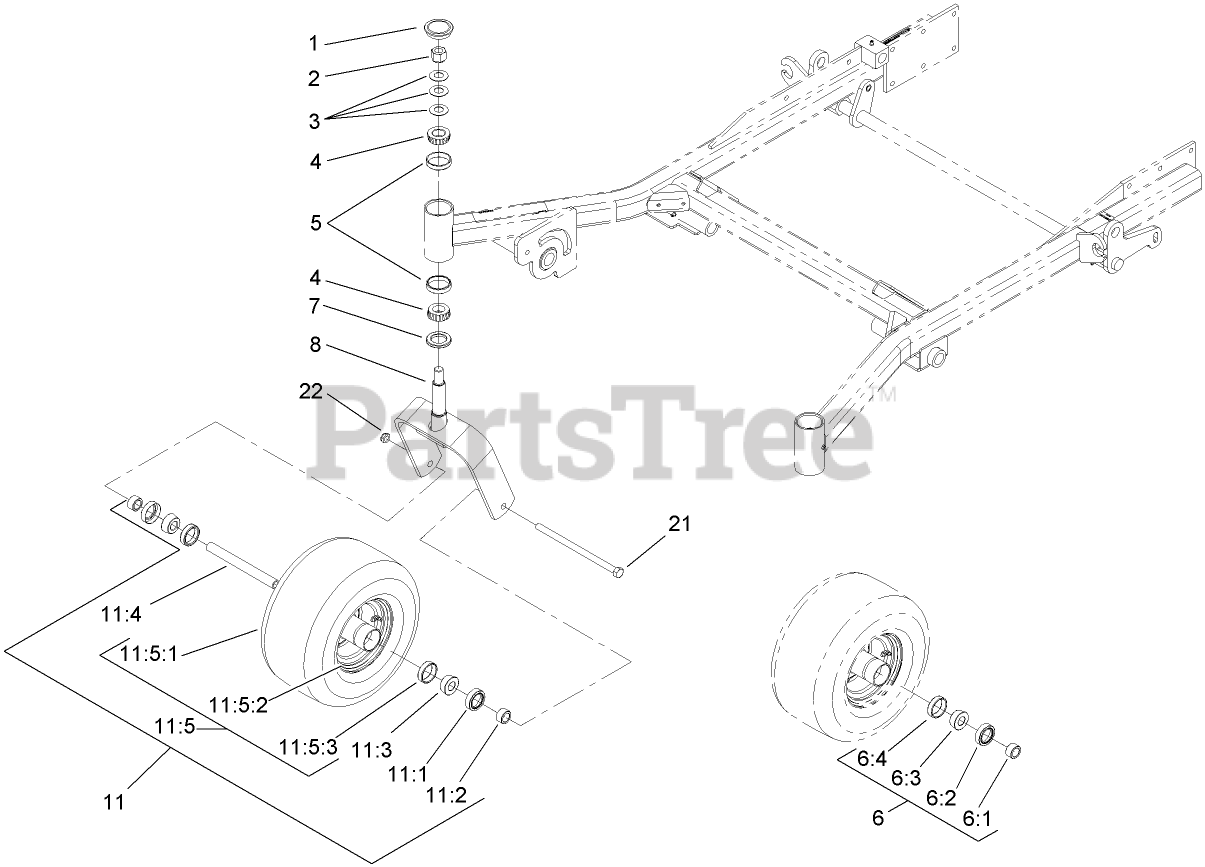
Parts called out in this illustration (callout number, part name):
1	CAP-GREASE
2	NUT-LOCK, NI
3	WASHER-BELLVILLE
4	BEARING-CONE, TAPERED
5	BEARING-CUP, TAPERED
6	CASTER WHEEL BEARING KIT
6:1	SPACER-BEARING
6:2	SEAL-BEARING
6:3	BEARING-CUP
6:4	BEARING-CONE, TAPER
7	SEAL-GREASE
8	CASTER
11	CASTER WHEEL ASM
11:1	SEAL-BEARING
11:2	SPACER-BEARING
11:3	BEARING-CONE, TAPER
11:4	SPACER-CASTER, FRONT
11:5	Wheel AND Tire ASM
11:5:3	BEARING-CUP
21	SCREW-HH
22	NUT-LOCK, NI
